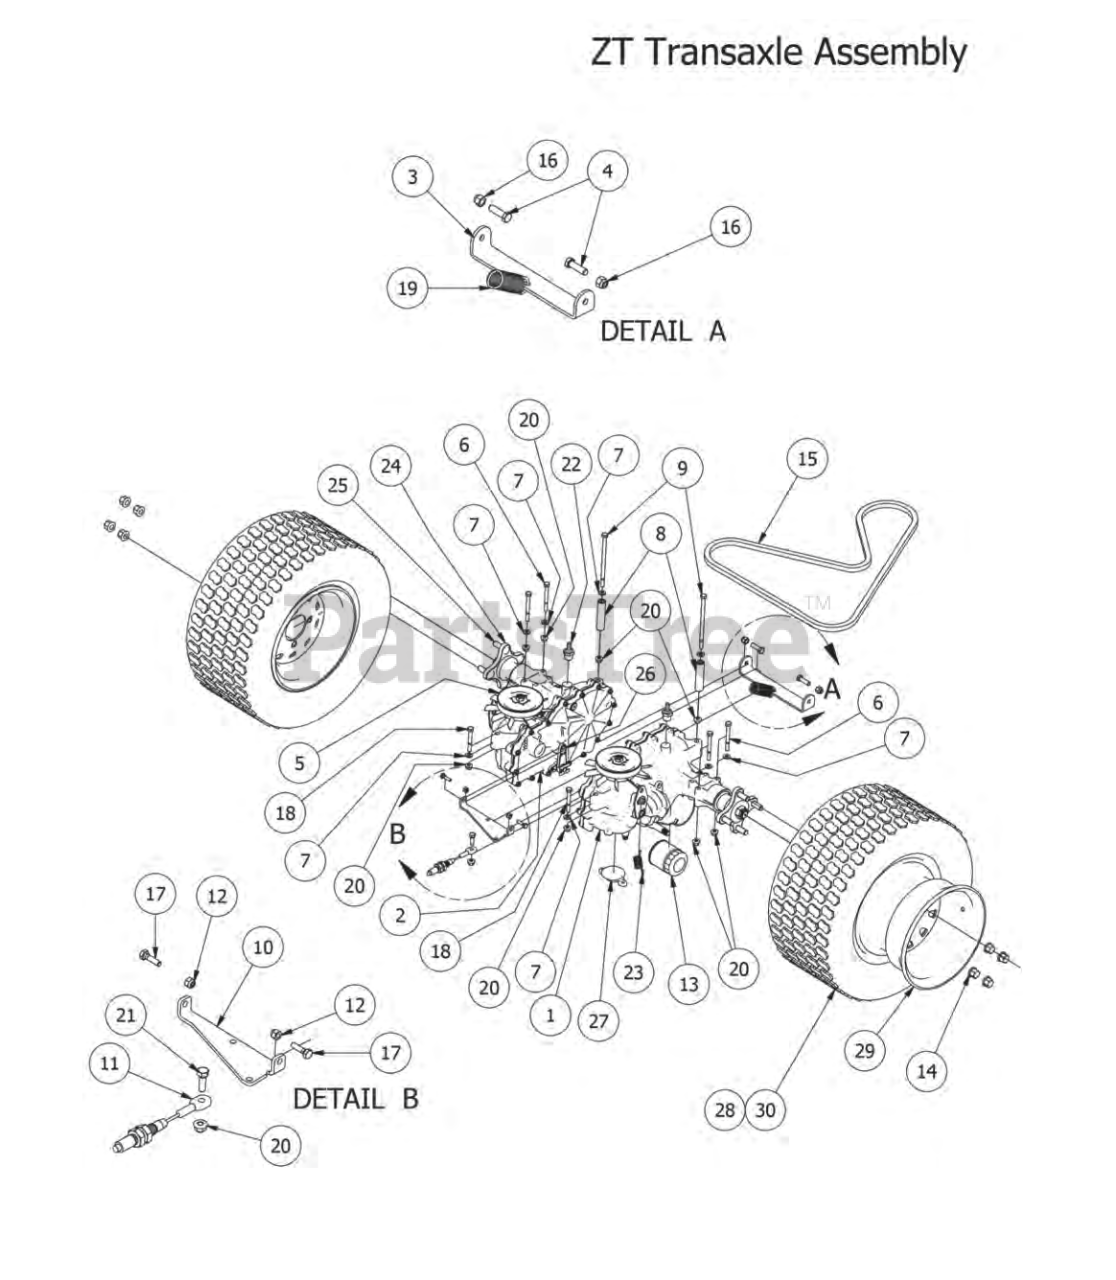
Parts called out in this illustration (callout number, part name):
1	Left ZT Transaxle
2	Right ZT Transaxle
3	Crossover Bar for ZT
4	3/8" x2" Hex Bolt
5	Fan/Pulley Kit
6	5/16" x 3" Hex Bolt
7	5/16" Flat Washer
8	3 1/4" Spacer
9	5/16" x 6" Bolt
10	ZT Crossover Brake Bracket
11	Brake Cable Stand On
12	1/4" Nylock Nut
13	Transaxle Filter
14	Acorn Lug Nut
16	3/8 Nylock Nut
17	1/4-20 x 1 GR 5 hex bolt zinc
18	5/16" x 2 1/2" Bolt
20	5/16" Nylon Flange Nut
21	5/16" x 1" Bolt
22	45 degree fitting
23	Transaxle Spring
24	ZT Transaxle Hub
25	Transaxle Wheel Studs
26	Transaxle Brake Lever
27	ZT Transaxle Charge Plate/With O'Ring
28	2014 ZT Assembly 22x11-10(Wheel and Tire)
29	2014 ZT Wheel Only 22x11-10
30	2014 ZT Tire Only 22x11-10
